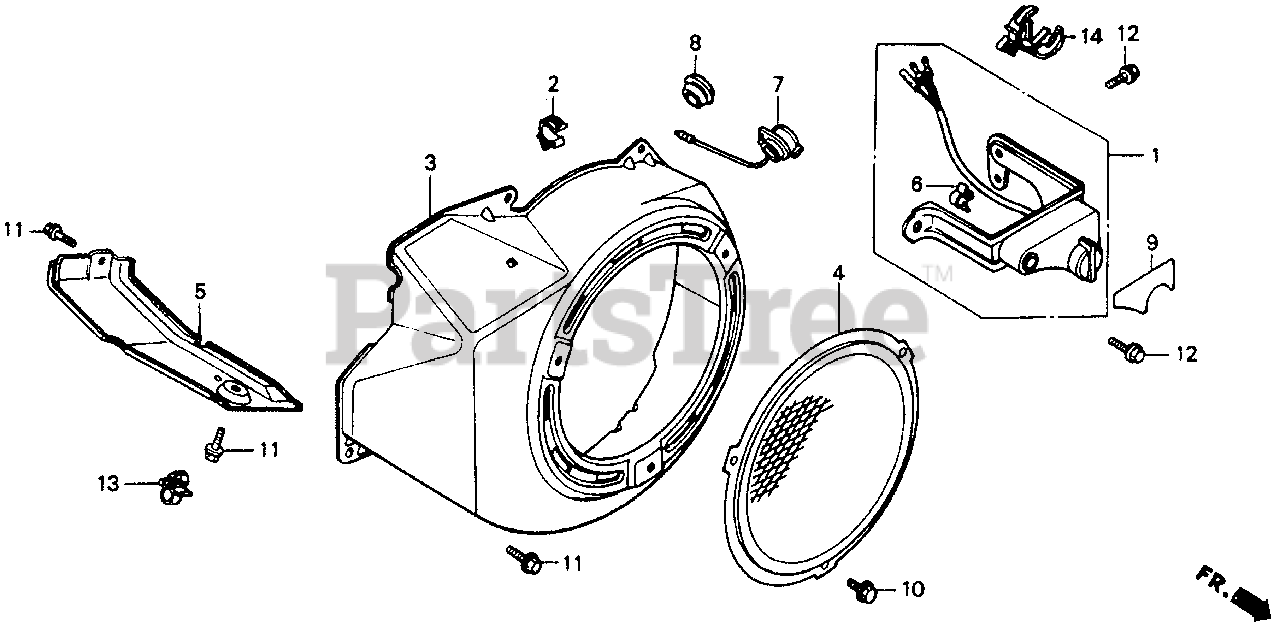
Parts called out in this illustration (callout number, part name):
1	ALERT UNIT, OIL
2	CLIP, TUBE
3	COVER, FAN *R8* (BRIGHT RED)
3	COVER, FAN *R280* (POWER RED)
5	SHROUD
6	CLIP, IGNITION WIRE (8MM)
8	GROMMET, DRAIN HOLE
9	MARK, OIL ALERT (EXTERNAL)
11	BOLT, FLANGE (6X12) (CT200)
12	BOLT, FLANGE (6X12) (CT200)
14	CLIP, WIRE HARNESS
